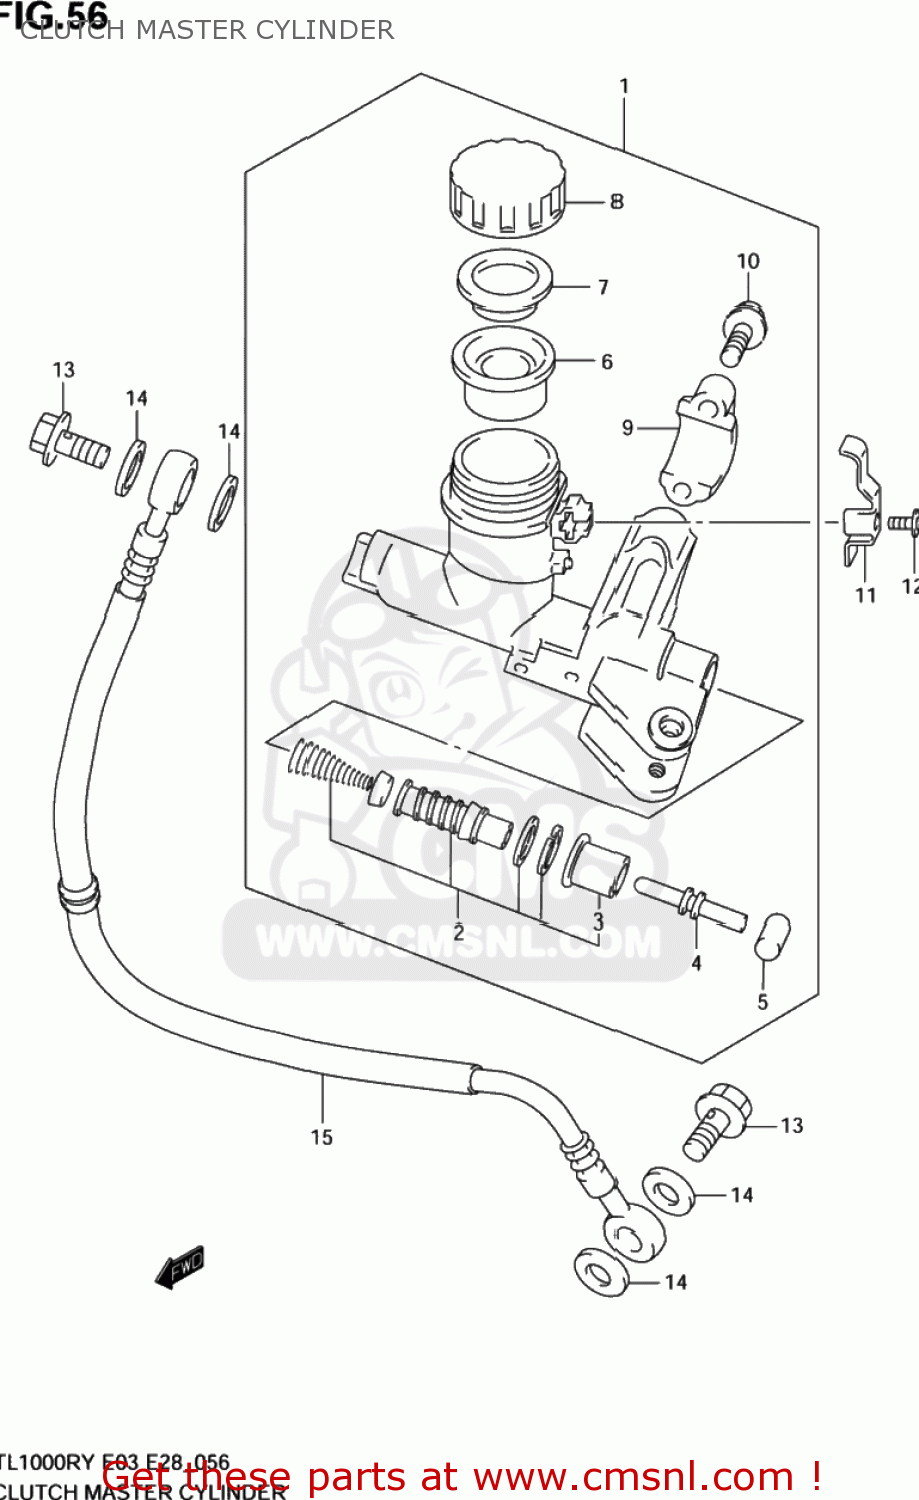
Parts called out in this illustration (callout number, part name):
1	CYLINDER ASSEMBLY,CLUTCH MASTER
2	PISTON & CUP SET
3	BOOT
4	PUSH ROD
5	BUSH
6	DIAPHRAGM
7	PLATE
8	CAP
9	HOLDER
10	BOLT(6X22)
11	PLATE,RESERVOIR TANK CAP
12	SCREW
13	BOLT UNION
14	WASHER(10X15X1.5)
15	HOSE,CLUTCH
